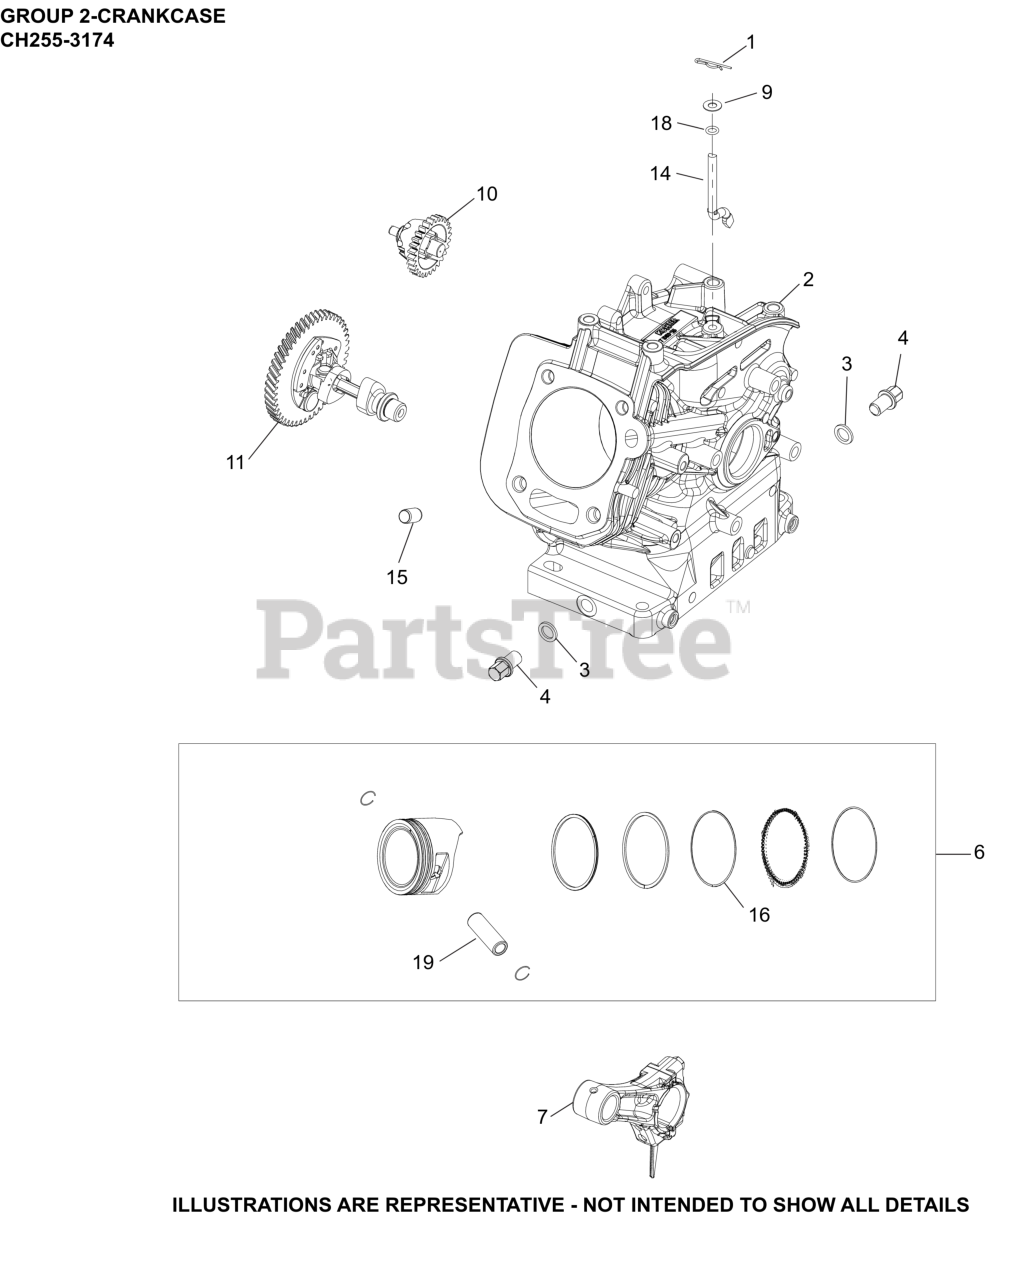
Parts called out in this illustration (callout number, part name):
1	CLIP, GOVERNOR SHAFT
2	CRANKCASE
3	WASHER, DRAIN PLUG
4	KIT, DRAIN PLUG
6	KIT, PISTON (STD)
7	ROD, CONNECTING ASSEMBLY
9	WASHER, FLAT (DIA 13mm O.D.)
10	GOVERNOR ASSEMBLY
14	SHAFT, GOVERNOR CROSS
19	PIN, PISTON
